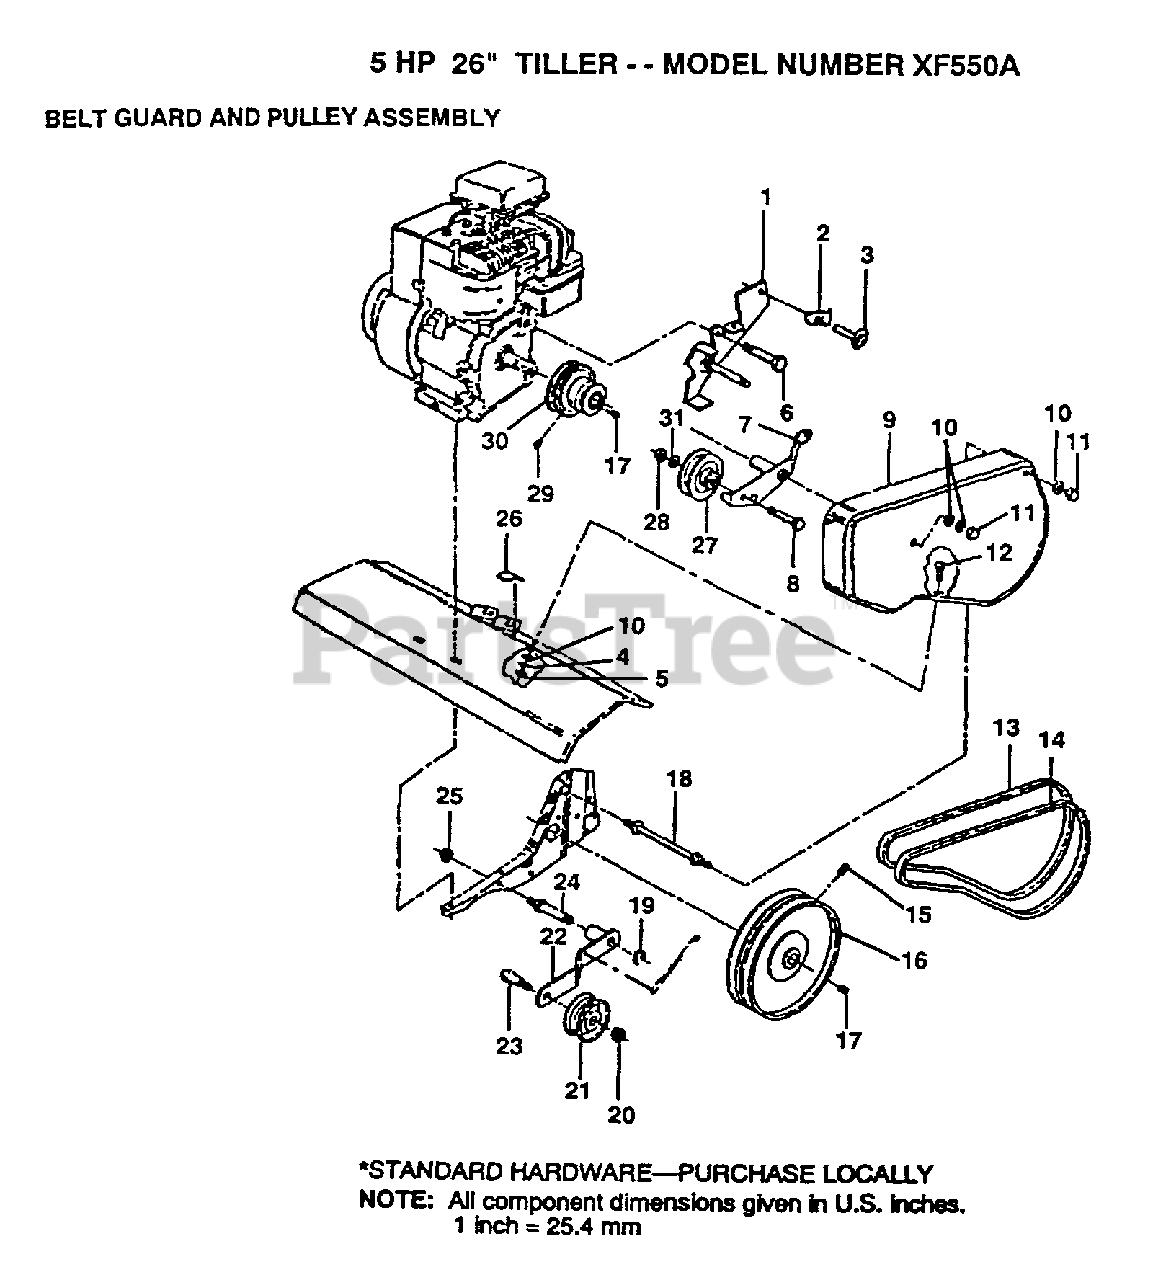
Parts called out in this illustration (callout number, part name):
2	CONDIUT CLIP T
4	LOCKWASHER
7	REV IDLER ARM TI
10	WASHER
11	NUT-CAP TI
12	BOLT T
15	SET SCREW
17	KEY T
18	BOLT TI
19	KLIP RING TI
20	NUT
22	IDLER ARM TI
24	SHAFT IDLER TI
25	JAM NUT TI
26	PAD IDLER TI
27	PULLEY W/SPACER
28	NUT.HEX.3/8-16UNC
29	SET SCREW
30	ENGINE PULLEY TI
31	WASHER
